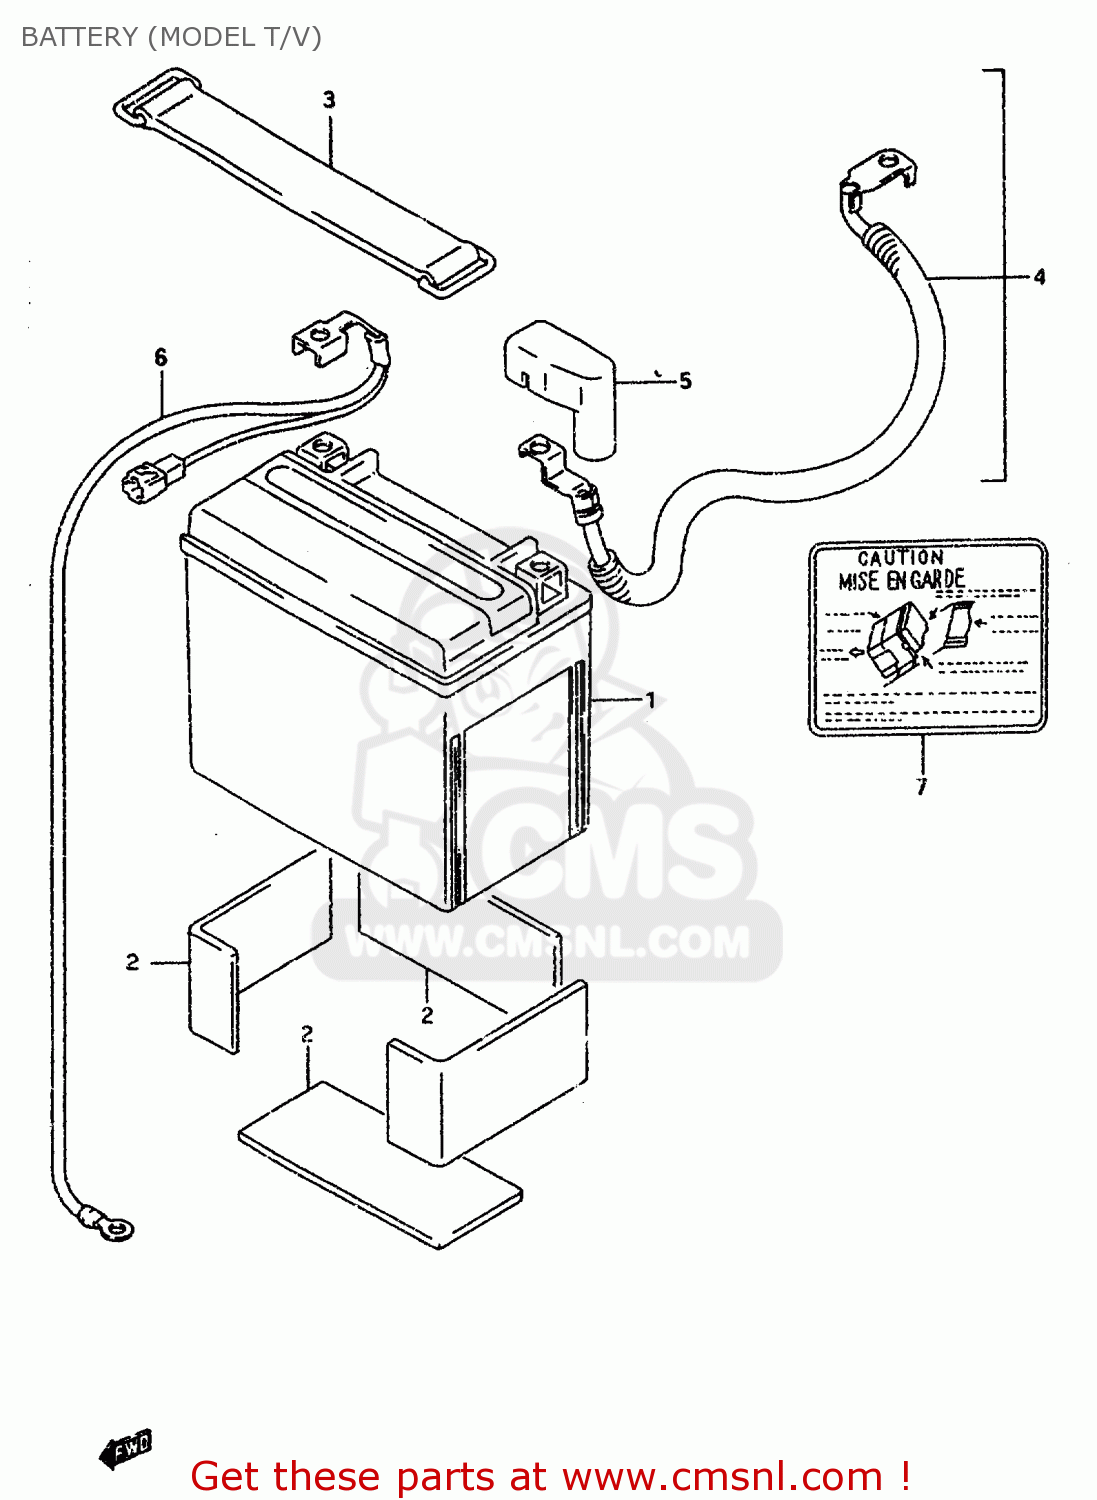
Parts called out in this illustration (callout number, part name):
1	BATTERY ASSY(YTX12-BS,12V10AH)
2	PROTECTOR(170X95X3.0)
3	BAND
4	WIRE,BATTERY PLUS LEAD
5	CAP,BATTERY PLUS TERMINAL
6	CAP,BATTERY PLUS
7	WIRE,BATTERY MINUS
8	PLATE,BATTERY CAUTION
